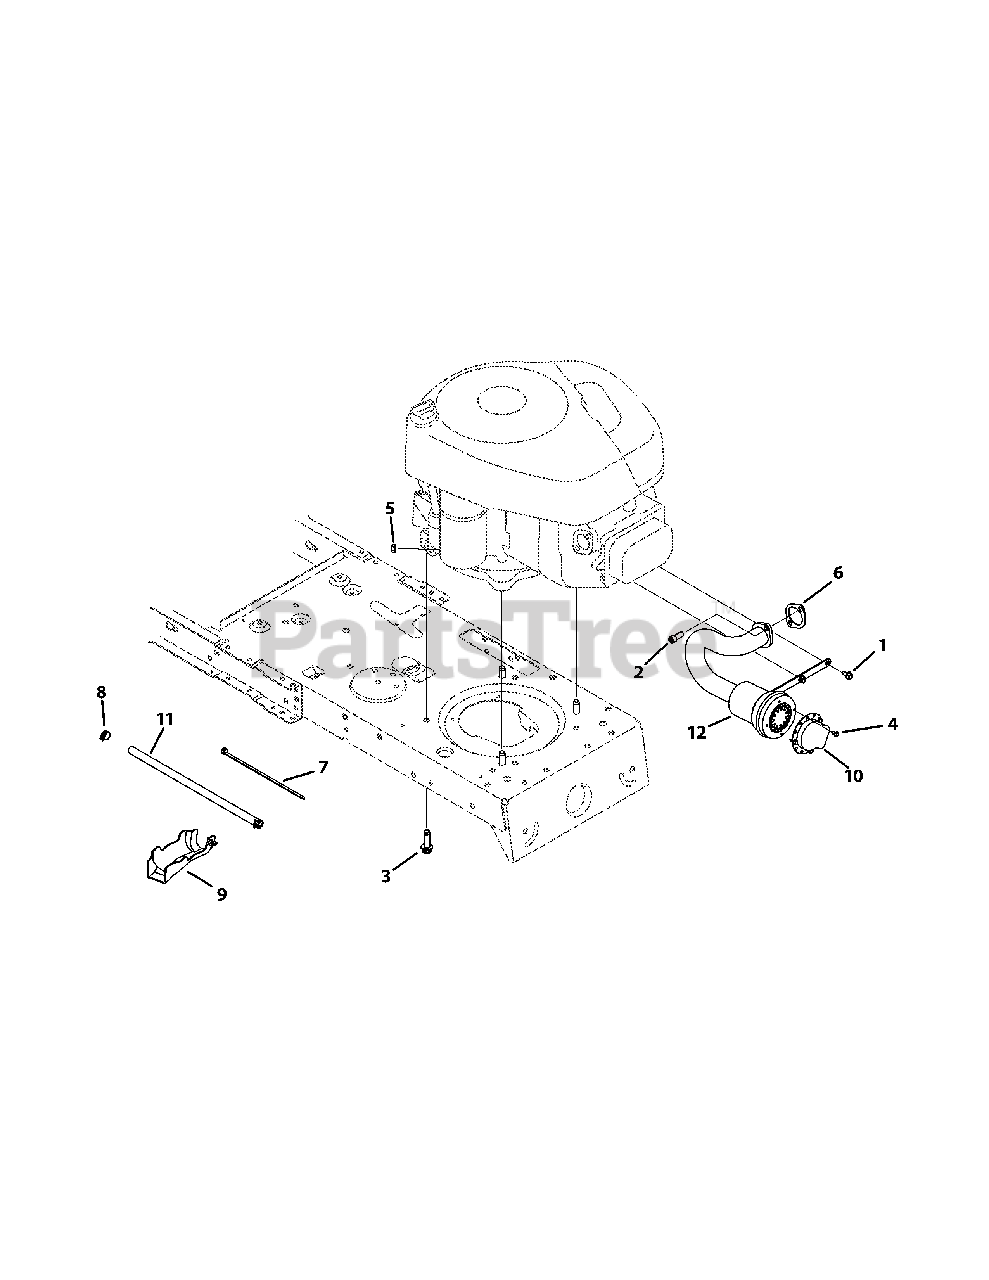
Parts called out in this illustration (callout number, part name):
1	Screw, 1/4-20 x .500
2	Socket Screw, 5/16-18 x .750
3	Screw, 3/8-16 x 1.0
4	Screw, 8-18 x .500
5	Sems Nut, 1/4-20
6	Exhaust Gasket, 10 HP Briggs
7	Cable Tie
8	Clamp Hose, .490 diameter
9	Oil Drain Sleeve
10	Muffler Deflector
11	Fuel Hose, Low Permeation
12	Muffler
